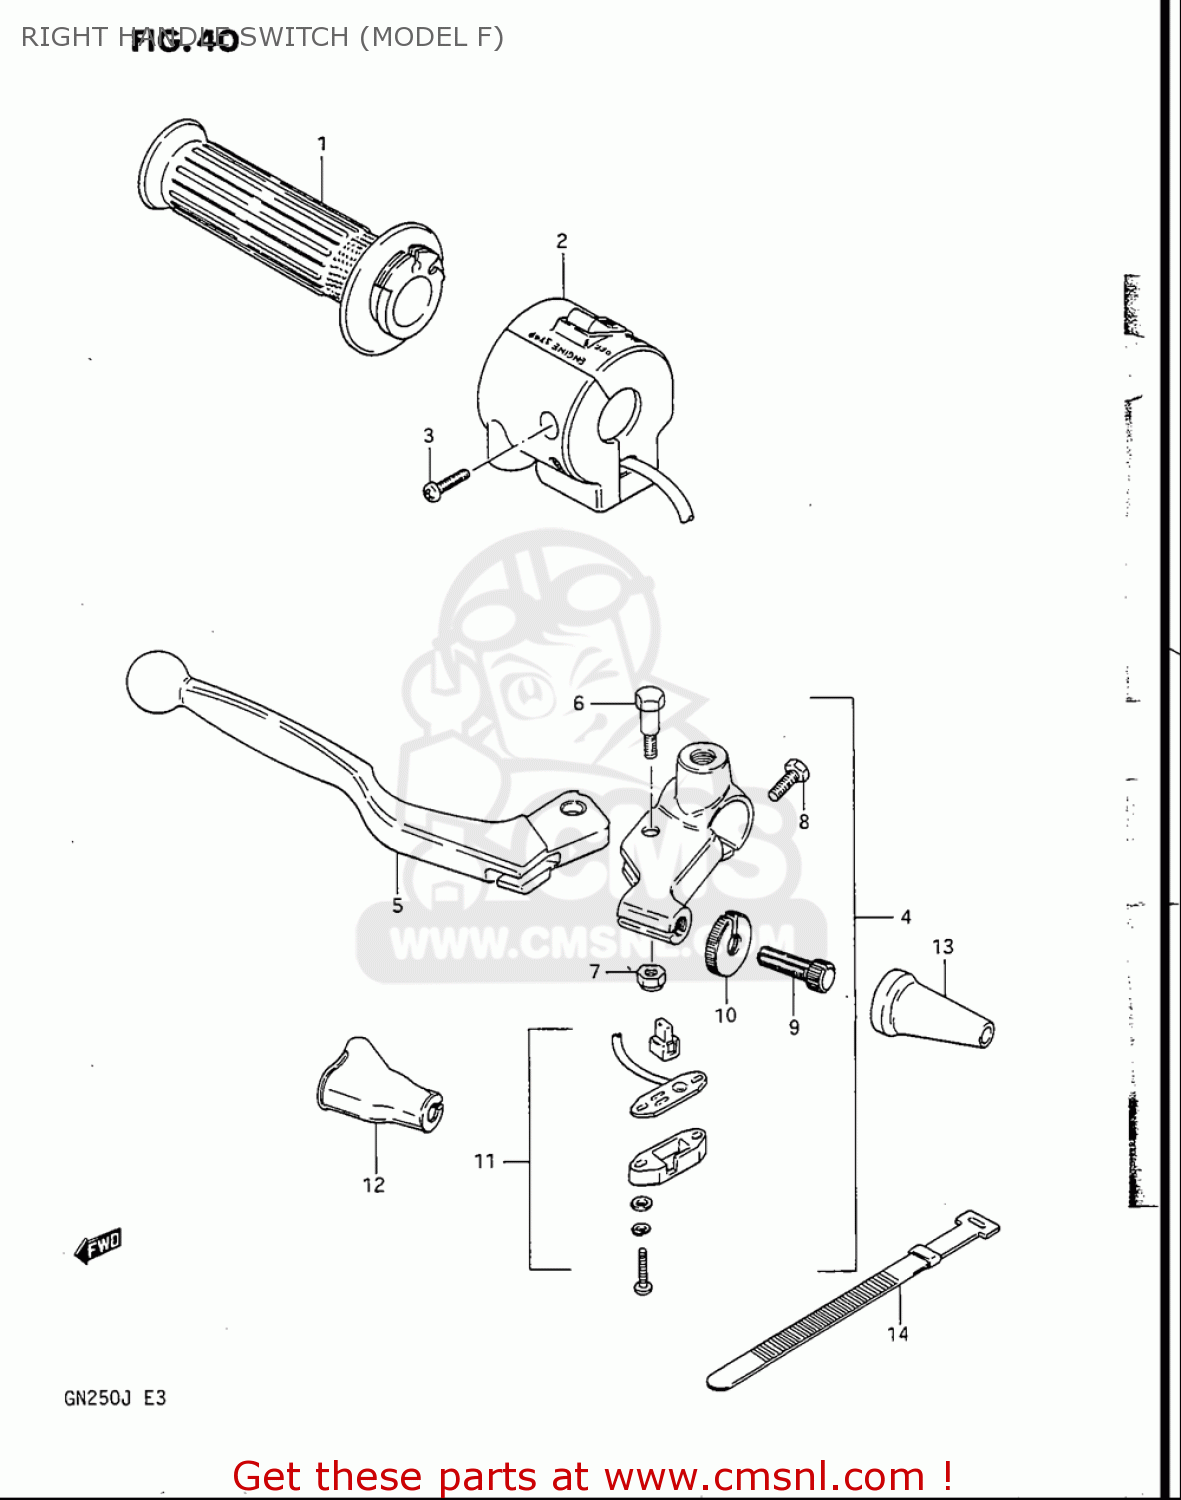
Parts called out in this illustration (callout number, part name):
1	GRIP,THROTTLE
2	SWITCH ASSY,HANDLE,R
3	SCREW(5X14)
4	LEVER ASSEMBLY,BRAKE
5	LEVER,BRAKE
6	BOLT,LEVER PIVOT
7	NUT 6MM
8	BOLT,CLUTCH LEVER HOLDER
9	ADJUSTER,CABLE
10	NUT,CABLE ADJUSTER
11	SWITCH ASSY,STOP
12	COVER,BRAKE LEVER DUST
13	BOOT,CLUTCH CABLE
14	CLAMP(L:120)
